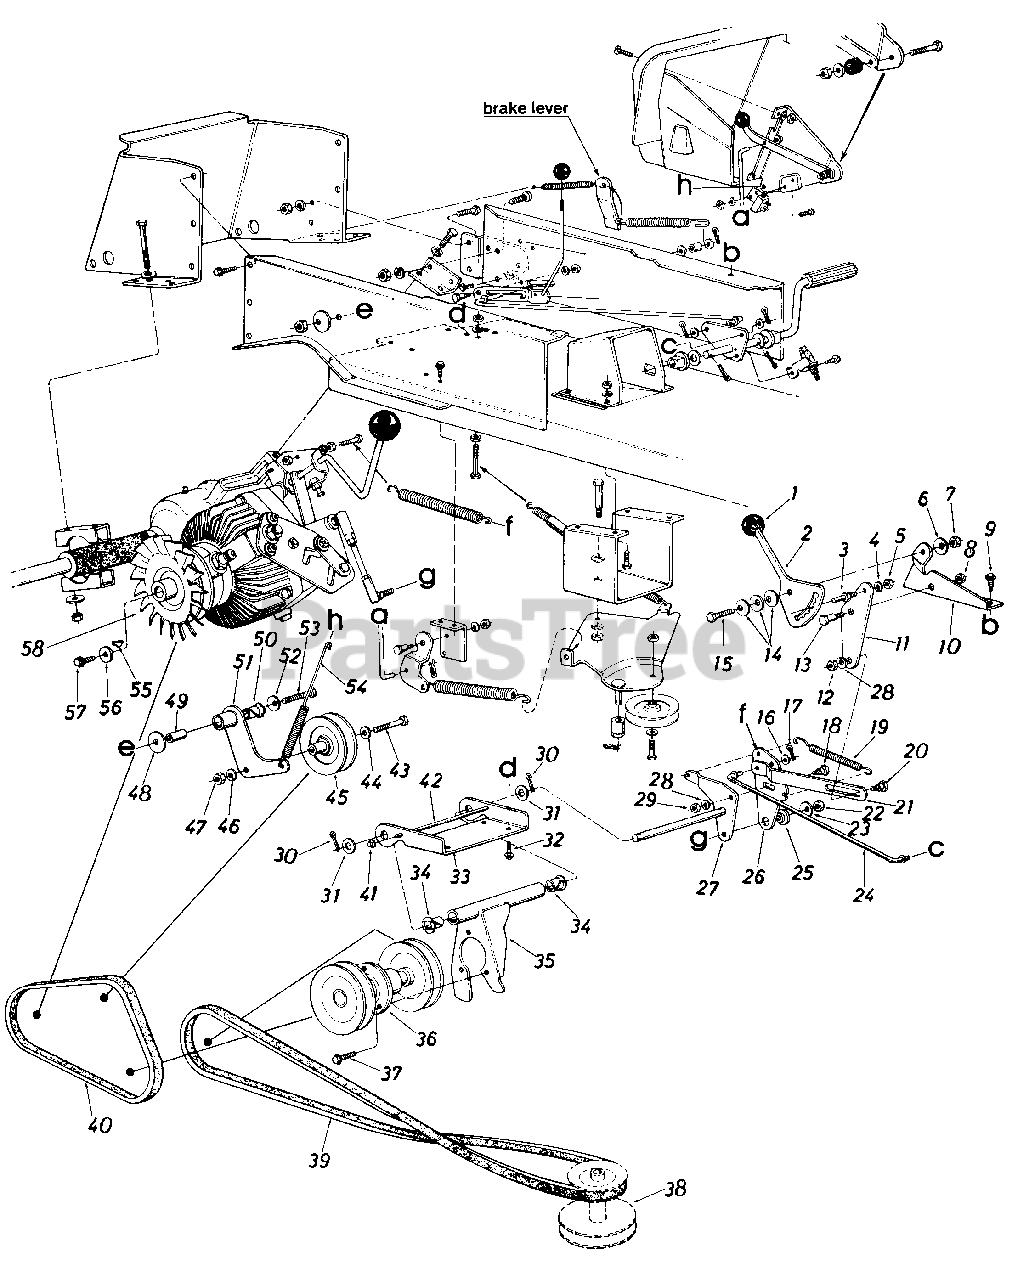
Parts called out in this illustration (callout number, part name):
1	"T" Gear Shift Knob
2	Speed Selector Cam
3	Hex Stud .250" Dia. x .62"
4	L-Wash. 1/4" I.D.
5	Hex Nut 1/4-20 Thd.
6	Bell-Wash. .400" I.D. x 1.13" O.D.
7	Hex Ins. L-Nut 3/8-24 Thd.
8	Hex Top L-Nut 3/8-16 Thd.
9	Hex Wash. Hd. S-Tap Scr. 1/4-20 x .75" Lg.
10	Speed Selector Mtg. Brkt.
11	Speed Selector Transfer Brkt.
12	Hex Nut 5/16-18 Thd.
13	Shld. Bolt .500" Dia. x .170
14	Bell-Wash. .39" I.D. x 1.13" O.D.
15	Hex Bolt 3/8-24 x 1.00" Lg.
16	Fl-Wash. .385" I.D. x .87" O.D.
17	Cotter Pin 3132" Dia. x .75" Lg.
18	shl8 Bolt .437 Dia. x .180
19	Extension Spring .50" Dia. x 2.75" Lg.
20	Shld. Bolt .437" Dia. x .180
21	Speed Selector Link
22	Hex Nut 3/8-24 Thd.
23	Bell-Wash .39" I.D. x 1.13" O.D.
24	Rod Speed Control .312" Dia.
25	Shld. Spacer .625" I.D.
26	Speed Cont. Transfer Swivel Brkt.
27	Speed Control Transfer Ass'y.
28	L-Wash. 5/16" I.D.
29	Hex Nut 5/16-18 Thd.
30	Cotter Pin 1/8" Dia. x 1.00" Lg.
31	Fl-Wash. .640" I.D. x 1.24" O.D.
32	Hex Wash S-Tap Scr. 1/4-20 x .50" Lg.
33	Idler Mtg. Brkt.
34	Flanged Nyliner Brg. .376 I.D. x .437
35	Mounting Brkt. Ass'y.
36	Jack Shaft Ass'y.
37	Hex Sems Bolt 5/16-18 x .75" Lg.
38	Engine Pulley 47 5" 1 D x 5.56" O.D.
39	'IV"-Belt 1/2" x 59.0" Lg.
40	"V"-Belt 1/2" X 32.0" Lg.
41	Push Cap
42	Rod 3116" Dia. x 7.12" Lg.
43	Hex Bolt 3/8-24 x 1.50" Lg.
44	Fl-Wash. .385" I.D. x .87" O.D.
45	Idler Pulley 4.0" O.D. x 518"-"V"
46	L-Wash. 3/8" I.D.
47	Hex Nut 3/8-24 Thd.
48	Bell-Wash. .40" I.D. x .87" O.D.
49	Spacer .38" I.D. x .62" O.D. x 1.87" Lg.
50	Flanged Nyliner Brg.
51	Idler Pivot Brkt. Ass'y.
52	Fl-Wash. .38" I.D. x .87" O.D.
53	Hex Bolt 3/8-24 x 2.00" Lg.
54	Extension Spring .56" O.D. x 7.75" Lg.
55	#9 Hi-Pro Key .316" X .75" Dia.
56	Fl-Wash. .505" I.D. x 1.0" O.D.
57	Hex Wash. Hd. S-Tap Scr. 1/4-20 x .75" Lg.
58	Trans. Pulley & Fan Ass'y.
